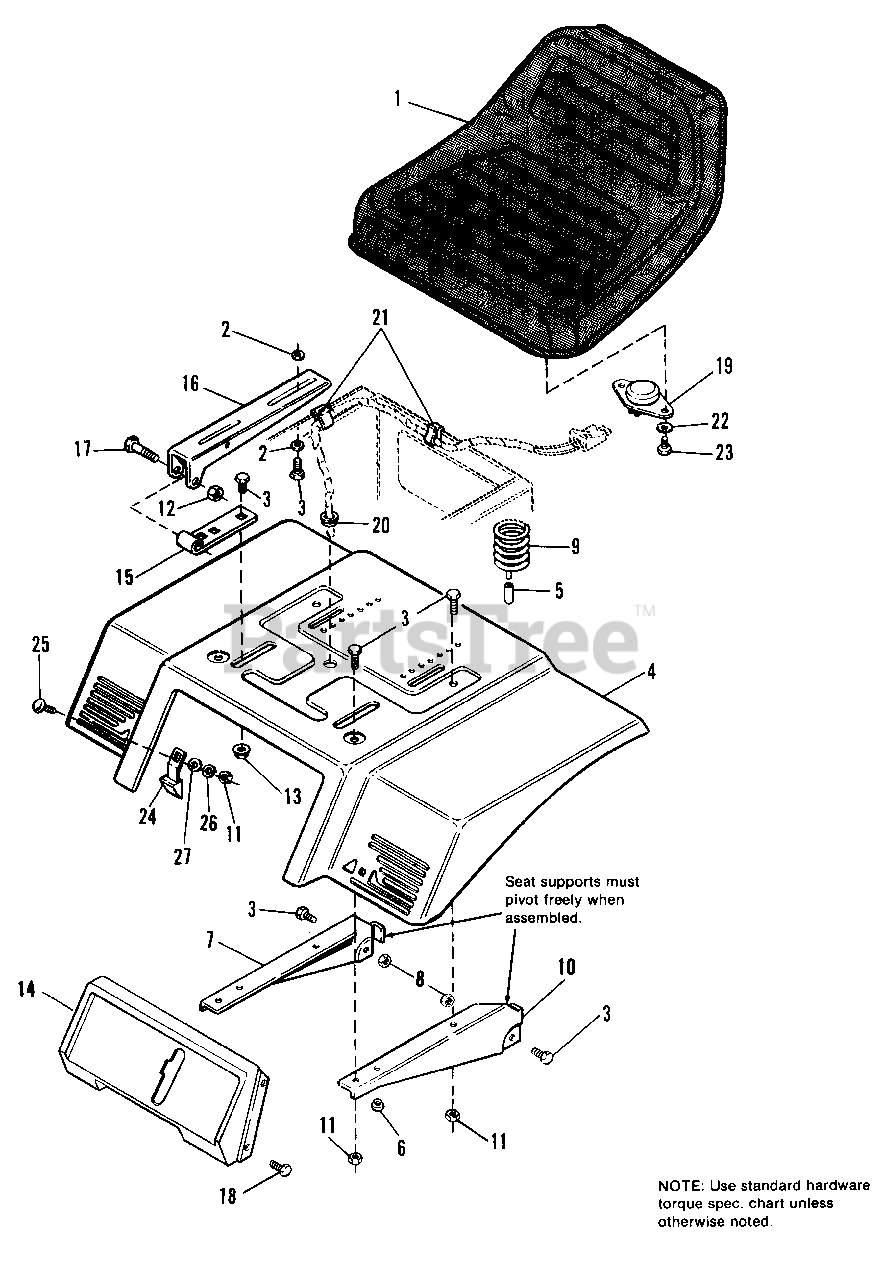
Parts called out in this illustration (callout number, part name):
2	WASHER, Plain, 11/32
3	CAPSCREW, Hex, 5/16-18 x 3/4
4	DECK, Seat
5	COVER, Wire
6	BUMPER, Plug
7	SUPPORT, Seat, R.H.
8	NUT, Hex, Lock, 5/16-18
9	SPRING, Seat
10	SUPPORT, Seat, L.H.
11	NUT, Hex, Full, 5/16-18
12	LOCKNUT, Hex, 3/8-16
13	Nut, Hex, Flange Whizlock, 5/16-18
14	PANEL, Shift
15	HINGE, Lower
16	HINGE, Upper
17	CAPSCREW, Hex, 3/8-16 x 2
18	SCREW, Hex, Taptite, 5/16-18 x 3/8
19	SWITCH, Seat
20	BUSHING, Snap
22	LOCKWASHER, 1/4 Ext. Tooth
23	SCREW, Rd. Hd., 1/4-20 x 3/4
24	SEAT LATCH ASSY.
25	BOLT, Carriage, 5/16-18 x 3/4
26	LOCKWASHER, 5/16
27	WASHER, 5/16
